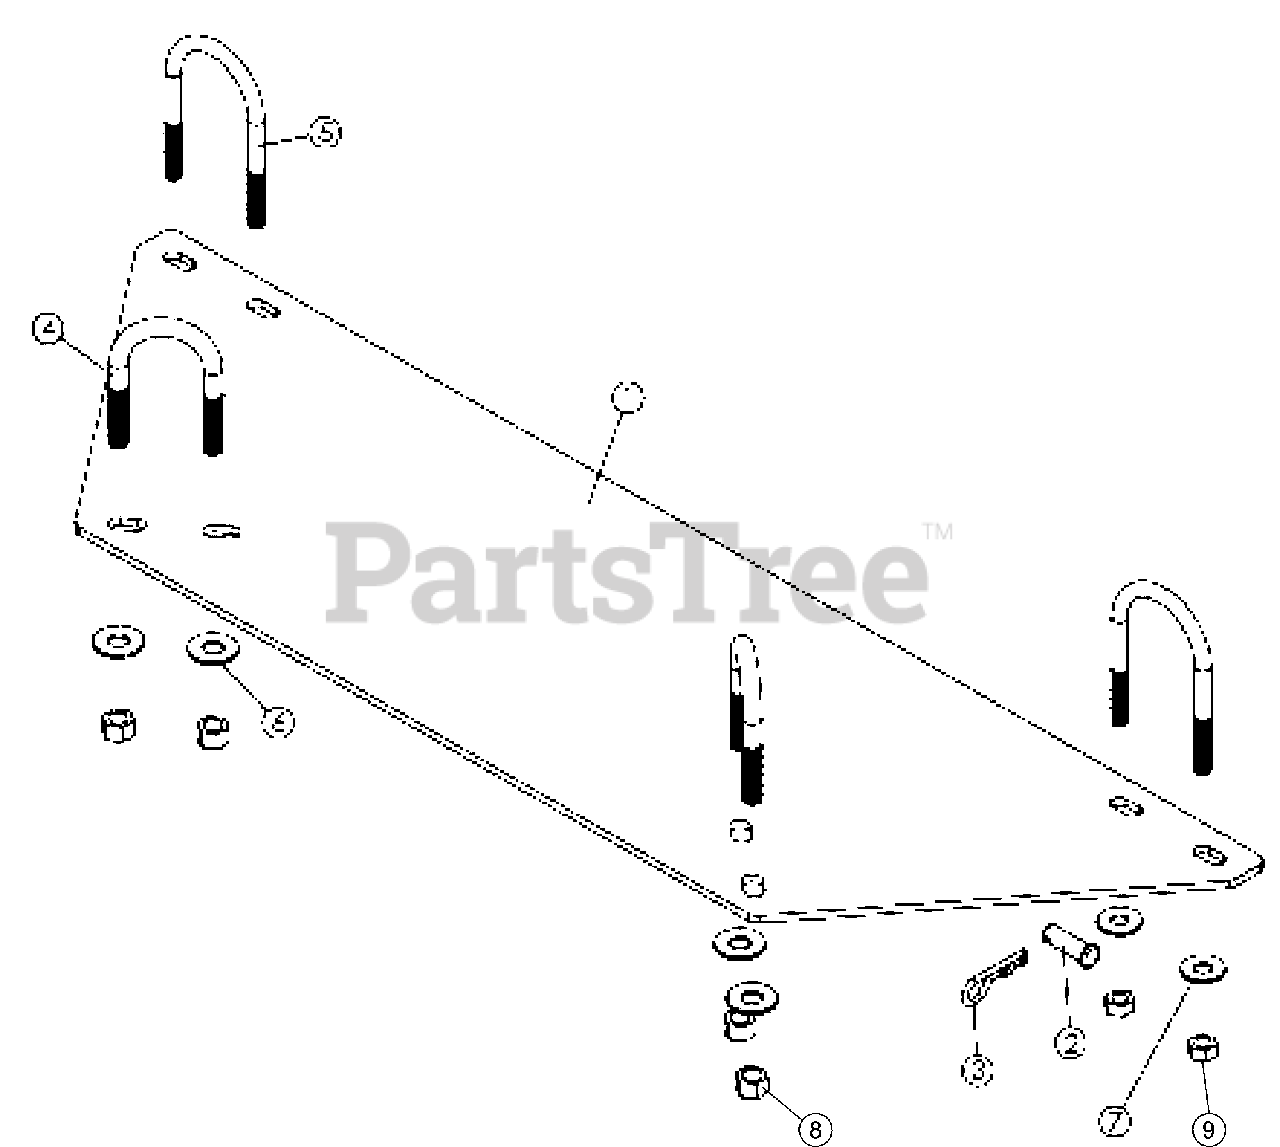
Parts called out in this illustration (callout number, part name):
1	BLADE MOUNT (ST Models)
2	3/8 CLEVIS PIN
3	PIN HAIR, No. 7 Clip
4	3/8 x 1-1/2 x 2-1/2 U-BOLT
5	5/16 x 2 x 3 U-BOLT
6	13/32 x 13/16 FLAT WASHER
7	11/32 x 11/16 FLAT WASHER
8	3/8-16 NYLON LOCK NUT
9	5/16-18 NYLON LOCK NUT
